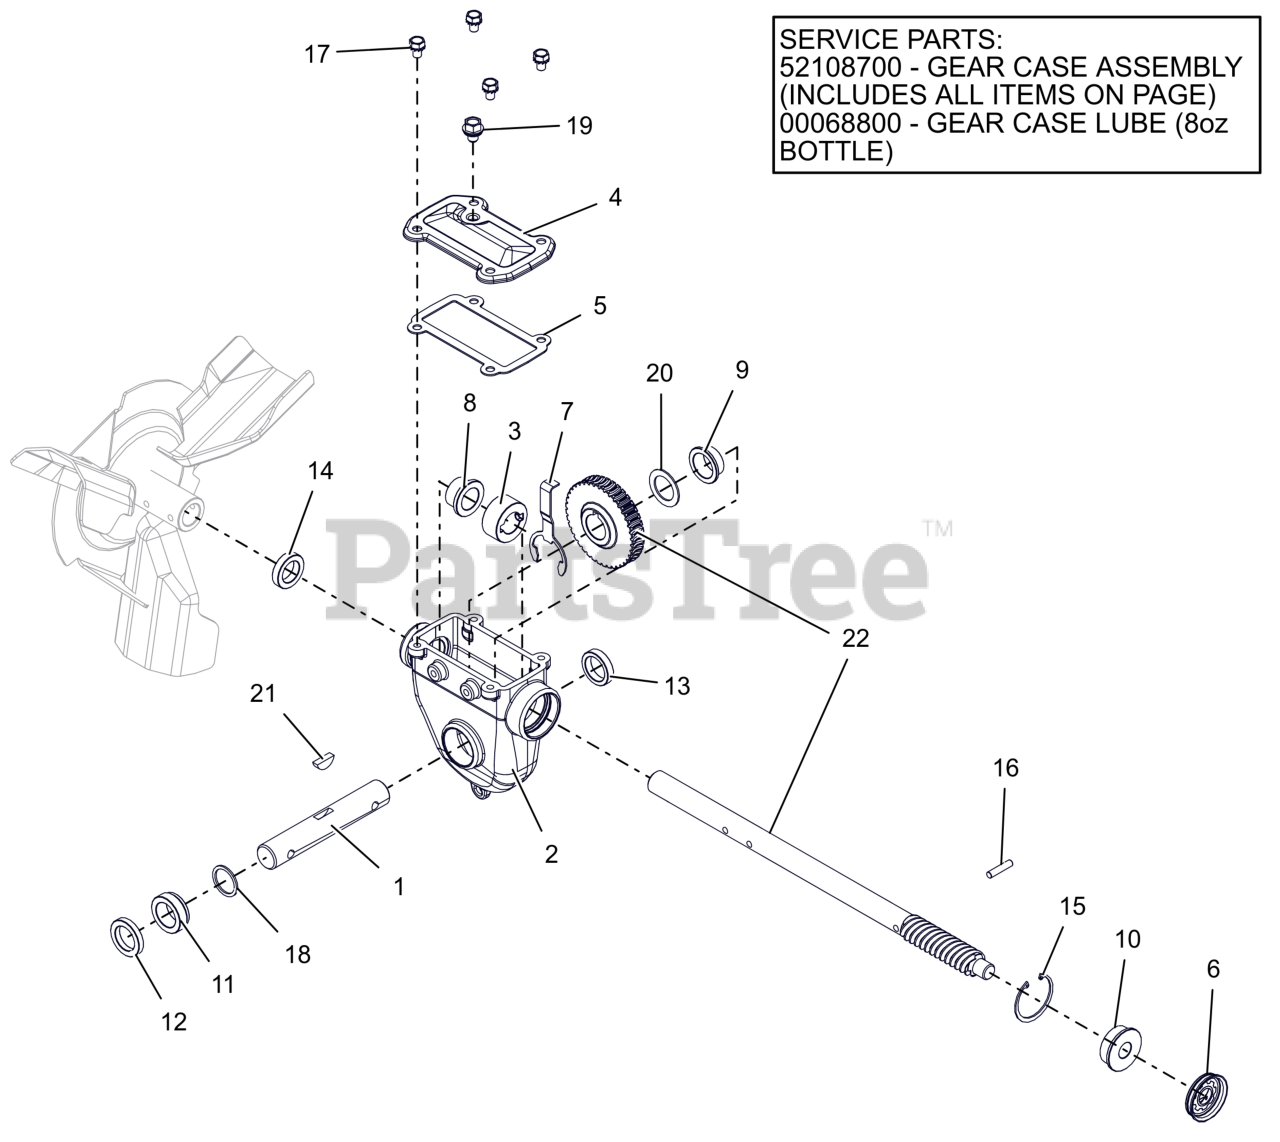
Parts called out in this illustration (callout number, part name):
1	RAKE SHAFT, SHORT-COMMON
2	GEARCASE, LARGE MACHINED
2	KIT, SERVICE - DLX GEAR CASE
2	ARIENS L3 LUBE, 8 OZ BOTTLE
3	THRUST COLLAR, .875"ID SLIPFIT
4	COVER, TOP - LARGE IRON
5	GASKET, TOP - LARGE GEARCASE
6	COVER, GEAR CASE 1.75"
7	BUSHING RETAINER, LARGE
8	BSHG-FLG .879X1.128X.75X1.45
9	BSHG-FLG 1.006X1.128X.555X1.45
10	BSHG-FLG .628X1.503X.58X1.725
11	BSHG-FLG LARGE, RIGHT
12	SEAL-OIL .999X1.500X.250 TBC29
13	SEAL-OIL .999X1.375X.312 TBC29
14	SEAL-OIL .873X1.375X.312 TBC29
15	RG-RTNG-INT 1.750X.062
16	PIN-STR .250X1.12 6150
17	BLT, SEMS .31-18X.50 G5 ZCC
18	WSHR, FLT 1.010X1.250X.068 ZCC
19	SCR, .380-15X.500 W/SEAL WASHER
20	WSHR, FLT 1.010X1.505X.062 ZCC
21	KEY-WDRF .25X.875 HRD #A
22	KIT, SERVICE-WORM SHAFT & GEAR
